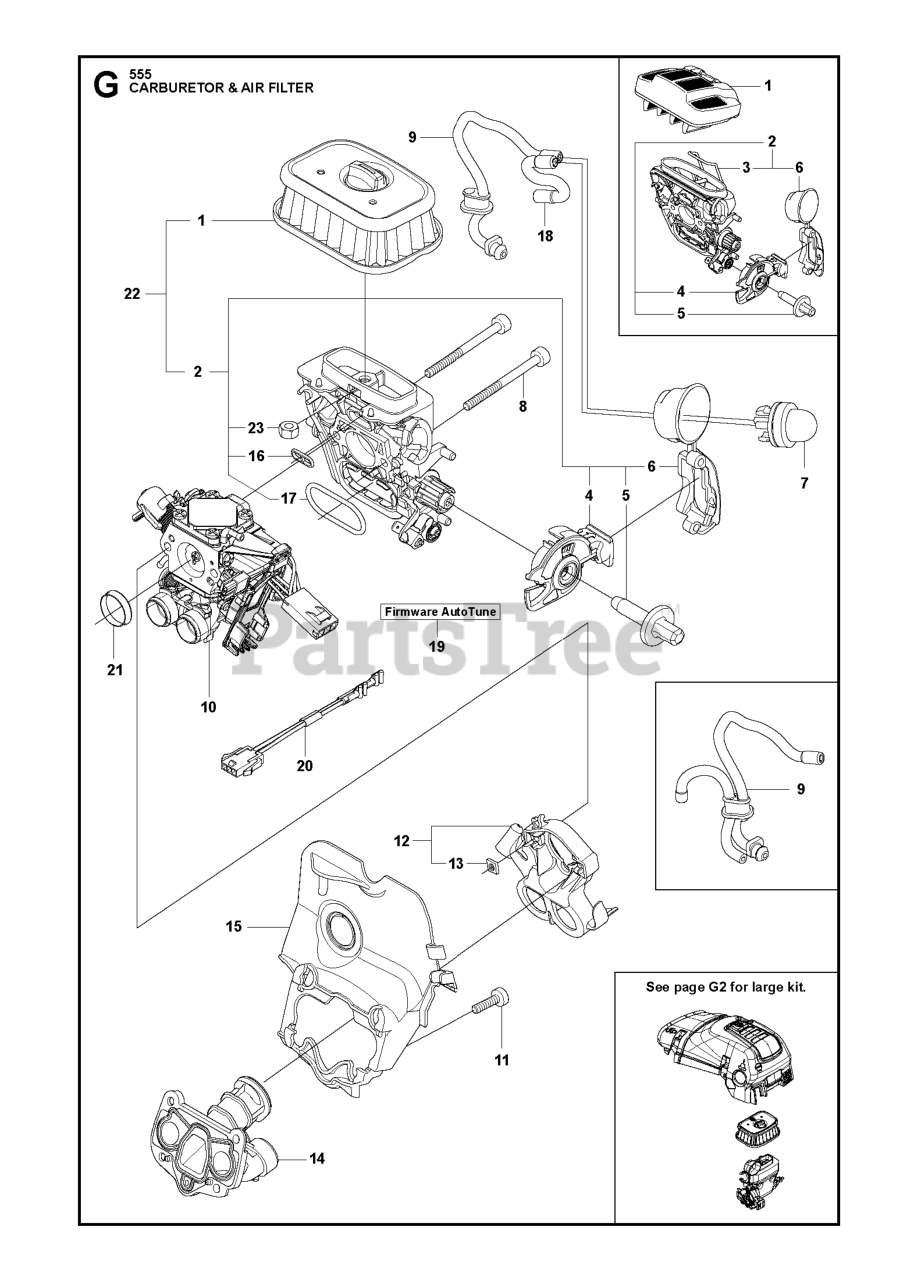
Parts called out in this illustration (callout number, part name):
1	AIR FILTER ASSY
1	AIR FILTER
1	AIR FILTER ASSY MESH 64 MICRON
1	AIR FILTER ASSY MESH 25 MICRON
1	AIR FILTER ASSY MESH NW
2	HOLDERS
2	FILTER HOLDER ASSY
3	SHACKLE
4	CHOKE CONTROL ASSY CHOKE/STOP
7	AIR PURGE BUBBLE
8	SCREW ITXSCM
9	FUEL HOSE
9	FUEL HOSE PURGE/TANKVENTILATIO
9	VENTILATING HOSE,KIT
10	CARBURETOR KIT 555 AUTOTUNE
10	CARBURETTOR KIT 60CC
11	SCREW ITXSCM M4X15 T27 12.9 T
12	FLANGE CARBURETTOR FLANGE
14	INLET PIPE
14	INLET PIPE COLD RESISTANT
15	INTERMEDIATE WALL
20	WIRING ASSY
21	SUPPORT SLEEVE
23	NUT
